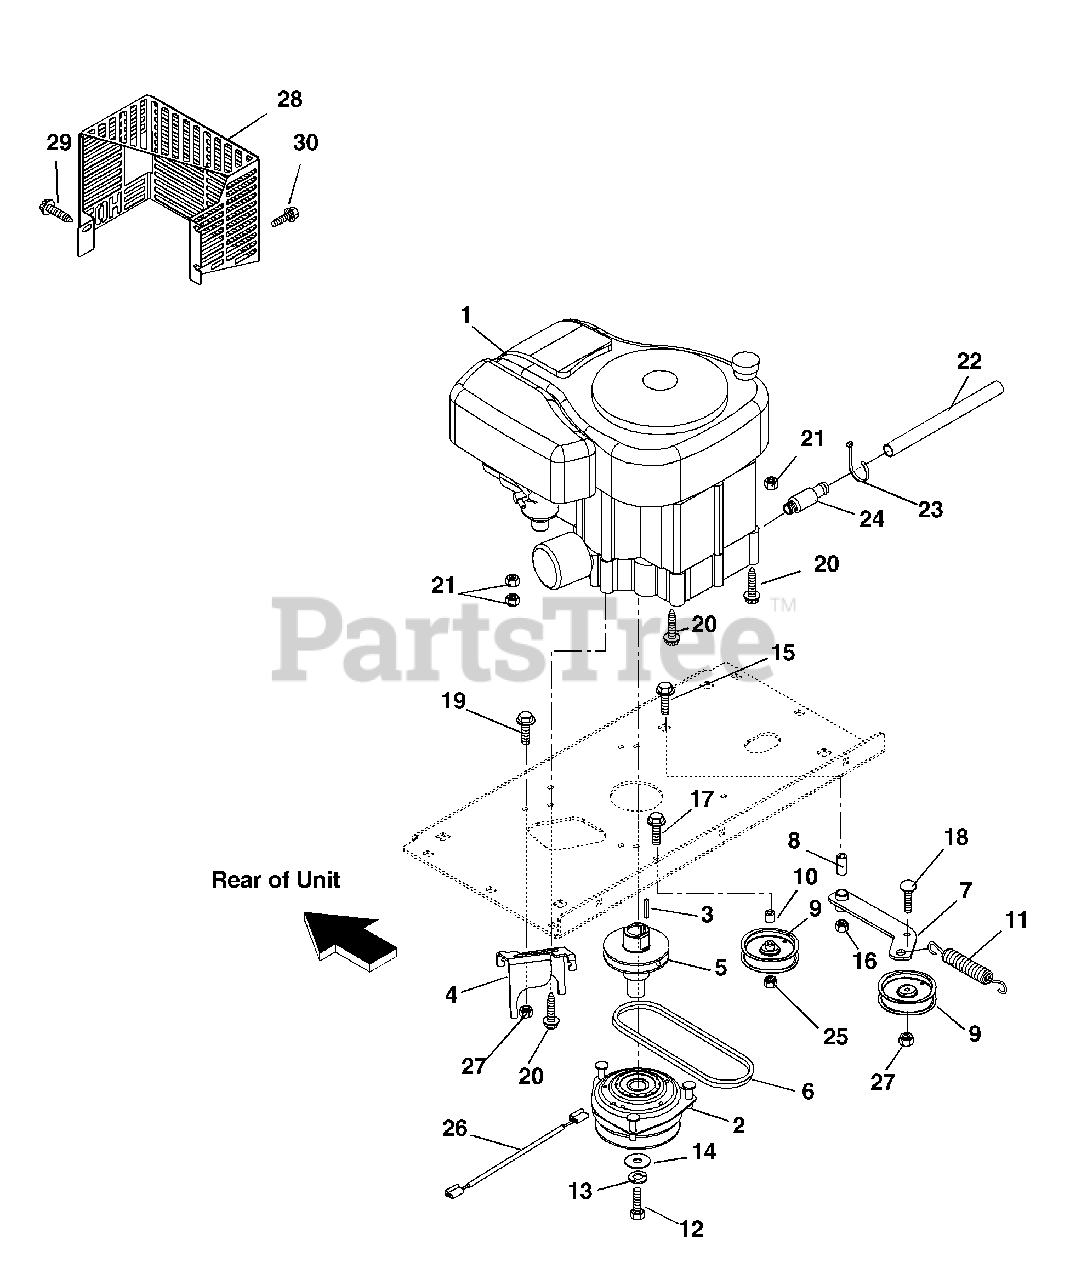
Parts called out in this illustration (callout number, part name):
1	15HP B&S ENGINE (SERVICE ASSY)
2	ELECTRIC CLUTCH/BRAKE (3.4AMP)
3	KEY-SQ .25 X 1.50 X .25 SAE
4	STOP, CLUTCH
5	EXTENSION SHAFT
6	V-BELT, HA-RAW EDGE
7	WMT, IDLER
8	BSHG-SLV .500X.750X1.560
9	IDLER-FLAT 4.00 X .38 NWHAMSHR
10	BSHG,SPCR .41 X .75 X .88 PM
11	SPRING, EXT
12	BLT-HEX .44-20X4.50 GR8 YWZC
13	@WSHR-LK .44X.109 REG YWZC
14	WSHR-FL-STL .469X2.00X.25 YWZC
15	@BLT-RDHDSQNK .50-13X2.50 G5YZ
16	@NUT-LK-TOP-FLG .50-13 YWZC
17	@BLT-RDHDSQNK .38-16X2.00 G5YZ
18	@BLT-RDHDSQNK .38-16X1.25 G5YZ
19	@BLT-HEX .38-16X1.00 GR5 YWZC
20	@BLT-HEX .31-18X1.75 GR5 YWZC
21	@NUT-LK-NYL-FLG .31-18 YWZC
22	TUBE, OIL DRAIN
23	CABLE TIE LG 5-1/2
24	VALVE, OIL DRAIN
25	@NUT-LK-CTR-JAM .375-16 YWZC
26	ADAPTER, CLUTCH HARNESS
27	@NUT-LK-NYL-FLG .38-16 YWZC
28	MUFFLER GUARD, 31CI
29	@SCR-TAP .25-20X.50 HWH TR YWZ
30	BLT-SERHFWH .312-18X.50 YWZC
